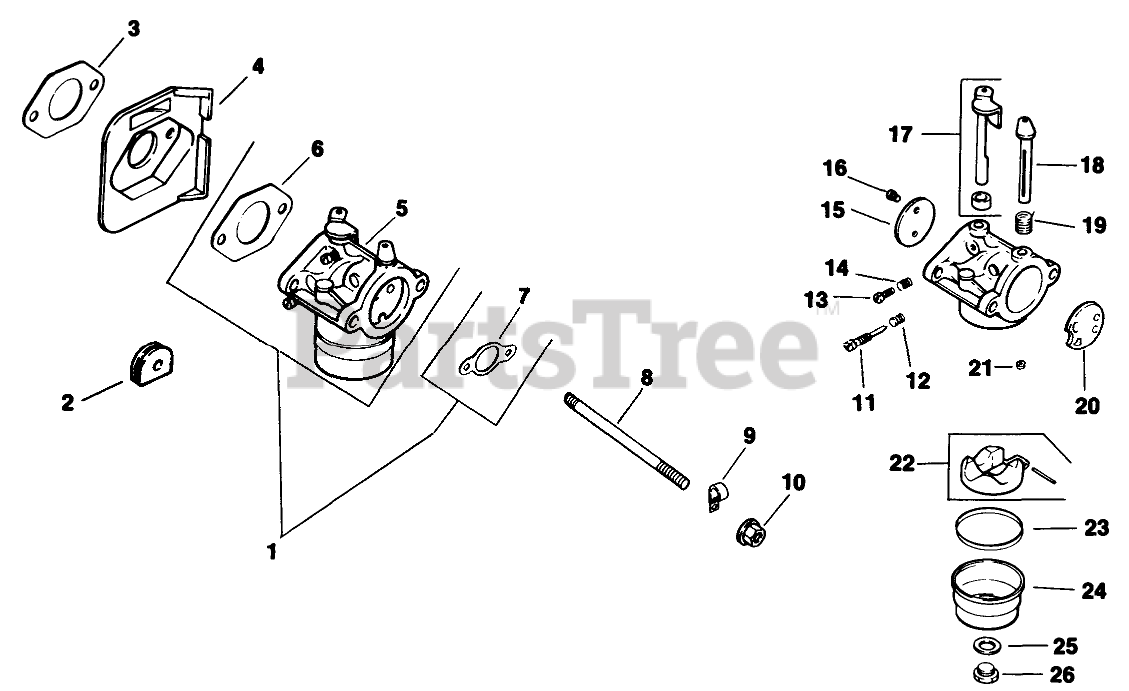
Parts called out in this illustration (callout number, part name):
1	Kit-Carburetor (Incl Ref. #5-7)
2	Grommet
3	Gasket
4	Deflector-Heat
5	Carburetor Assembly (Incl Ref. #11-26)
6	Gasket
7	Gasket
9	Clamp
11	Needle-Idle
12	Spring-Idle
13	Screw-Idle
14	Spring-Idle
15	Plate-Throttle
16	Screw-Throttle Plate
17	Shaft-Throttle
18	Shaft-Choke
19	Spring
20	Plate-Choke
21	Jet-Main
22	Kit-Float
23	Gasket-Bowl
24	Bowl
25	Gasket
26	Screw-Bowl
